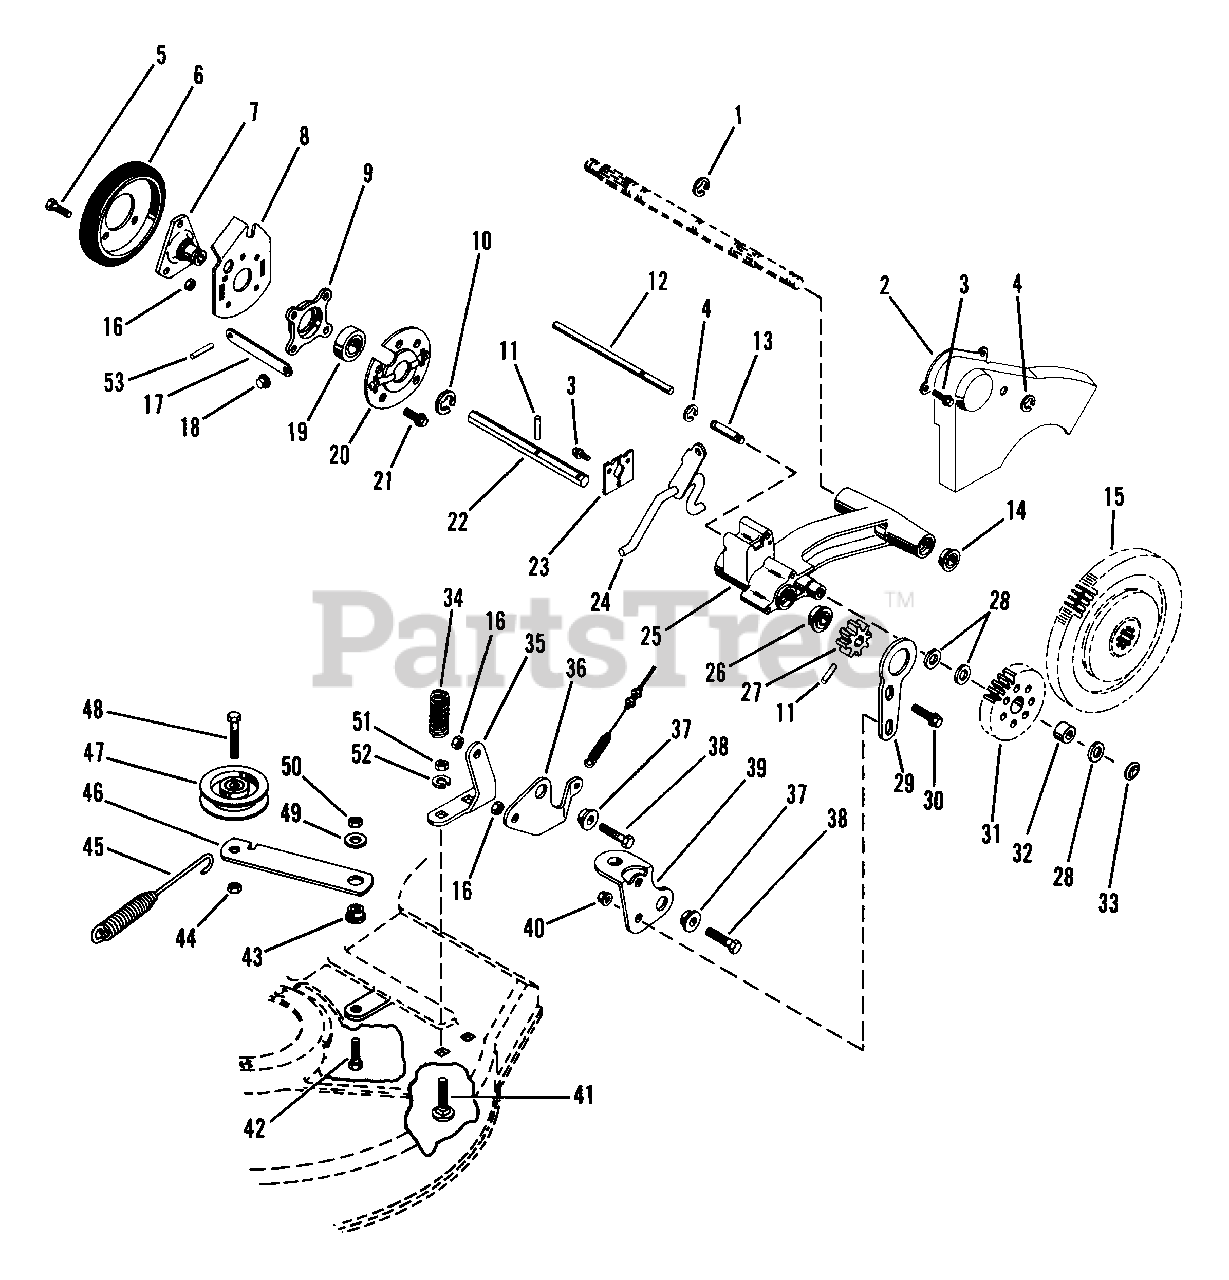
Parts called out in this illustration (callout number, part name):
1	RG-RTNG-EXT .750X.042
2	GEAR COVER
3	SCR-TAP 12-24X.50 HWH PL TR
4	RG-RTNG-EXT .438X.035
5	BLT-HEX .25-20X.50 PL GR2
6	FRICTION DISC
7	FRICTION WHEEL HUB
8	BEARING PLATE
9	BEARING RETAINER
10	RG-RTNG-EXT 1.00X.042
11	PIN-ROLL .188X.88
12	ROD - GUIDE
13	SHAFT - IDLER
13	SHAFT-IDLER
14	BRG-BALL .750X1.50X.44
14	BRG-BALL .752X1.50X.50
15	DIFFERENTIAL ASSEMBLY
16	NUT-LK-CTR .250-20 PL
17	SHIFT LINK
18	PUSH NUT, .25
19	BRG-BALL 1.0X2.0X0188
19	BRG-BALL 1.0X2.0X.56
20	BEARING RETAINER
21	SCR-TAP 10-24X.375 HWH PL TR
21	TAPTITE M5-0.8X16MM H-FL-PL
22	HEX SHAFT
23	RETAINER PLATE
24	SHIFT ARM WELDMENT
25	DRIVE MOUNT
26	BRG-BALL .562X1.38X.44
26	BRG-BALL .562X1.375X.437
28	WSHR-FL-STL .505X.880X.072 PL
29	CLUTCH COLLAR
30	BLT-SERHFWH .25-20X.50 PL
31	IDLER GEAR ASSEMBLY
31	IDLER GEAR
32	BRG-NEEDLE .500X.688X.625
32	BRG-BALL .500X1.38X.437
33	RETAINER
34	SG-COMP .086X.625X3.44
35	MOUNTING BRACKET
36	CLUTCH ARM
37	BSHG-FLG .265X.437X.250X.750
38	BLT-HEX .25-20X.63 PL GR2
40	NUT-LK-FLG .250-20 PL
41	BLT-RDHDSQNK .312-18X.62SHTPL
42	BLT-HEX .31-18X.75 PL GR2
43	BSHG, FLG .325X.499X.26X.88
44	NUT-LK-CTR .375-16 GR A PL
45	SG-TENS .043X.44X3.31 WLD 5.8
46	IDLER ARM
47	IDLER-FLAT 1.88 X .38 NWHAMSHR
48	BLT-HEX .38-16X1.50 PL GR2
49	WSHR-FL-STL .323X.625X.062 PL
50	NUT-LK .312-18 GR A PL
51	NUT-HEX .312-18
52	WSHR-LK .312X.097 PL HVY
53	PIN-ROLL .125X.50
53	PIN-ROLL .125X.63
